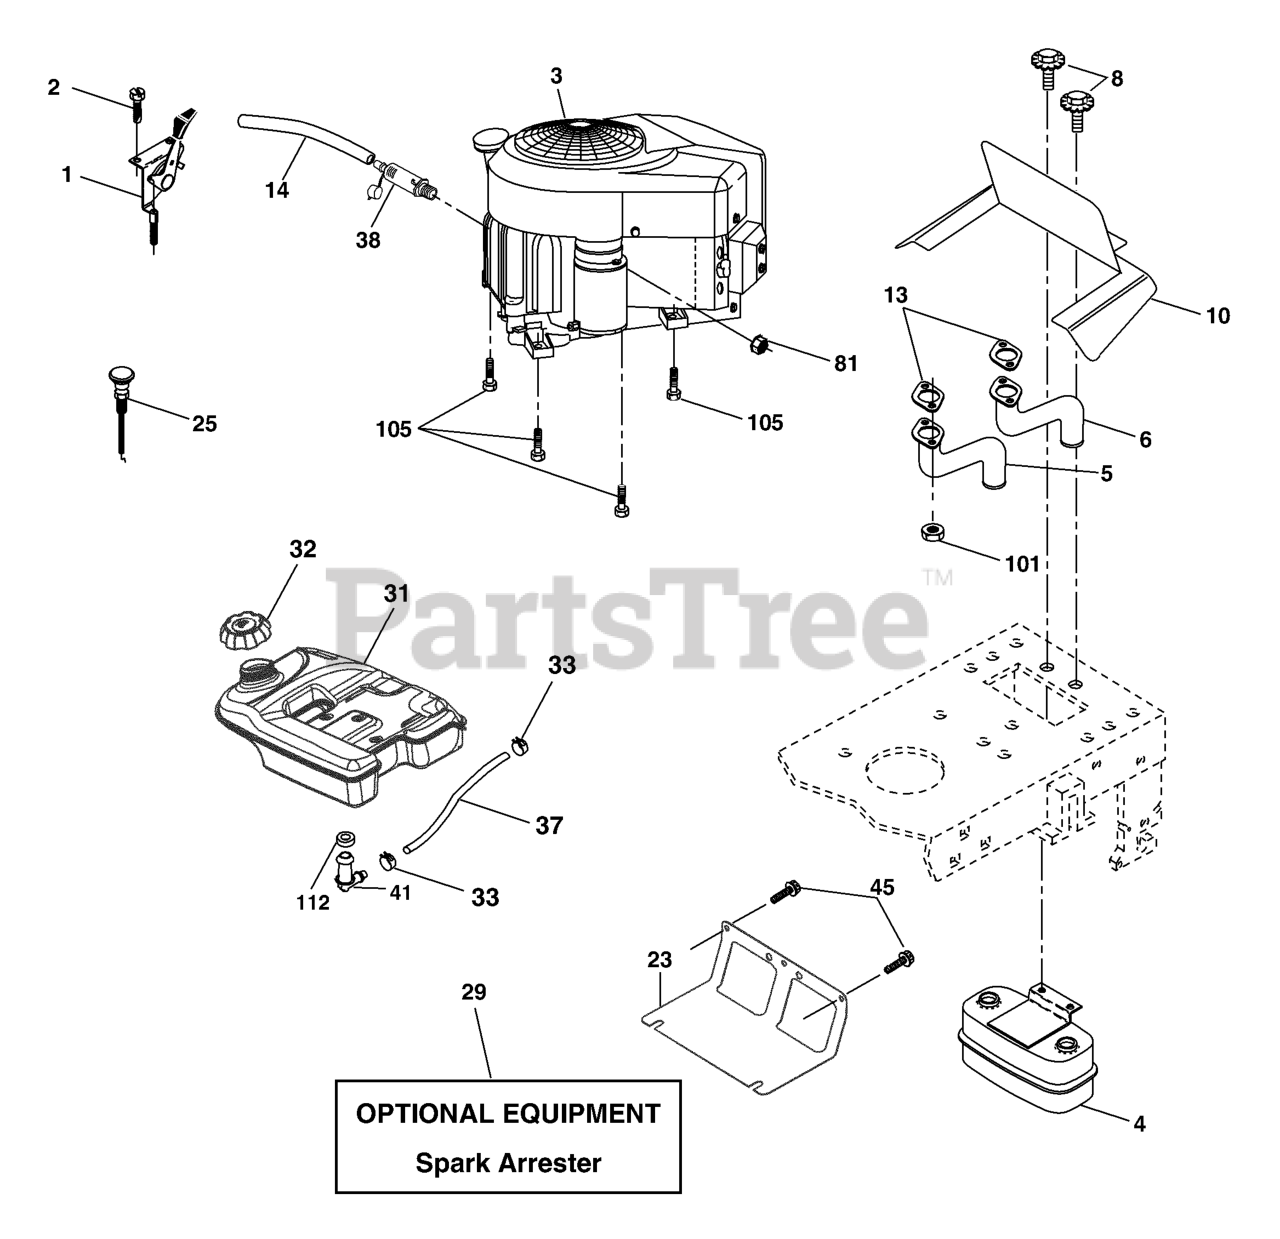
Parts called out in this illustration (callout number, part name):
1	CONTROL, THROTTLE
2	SCREW
4	MUFFLER.TWIN.CYL.LOW.TONE
5	EXHAUST.TUBE.LH.KAWASAKI.
6	EXHAUST.TUBE.RH.KAWASAKI.
8	BOLT.5/16-18UNCX3/4 W/SEMS.BLK
10	RP SHIELD HEAT MUFFLER
13	Gasket Muffler
14	TUBE, DRAIN OIL ASM.
23	SHIELD.BROWNING.DBR.GUARD
25	THROTTLE CONTROL
26	Nut, Keps 3/8-24 unf
29	KIT.SPARK ARRESTOR 794945 B&S
31	4.0 REAR FUEL TANK
32	TANK CAP
33	HOSE CLAMP
37	REPL BY 532 00 85-43
38	Plug Drain Oil
41	STEM FUEL TANK
45	SCREW, 3/8-16X3/4
81	NUT
101	NUT.HEX.FLANGE.TOPLOCK
105	SCREW 3/8-16X1
112	BUSHING OUTLET T
